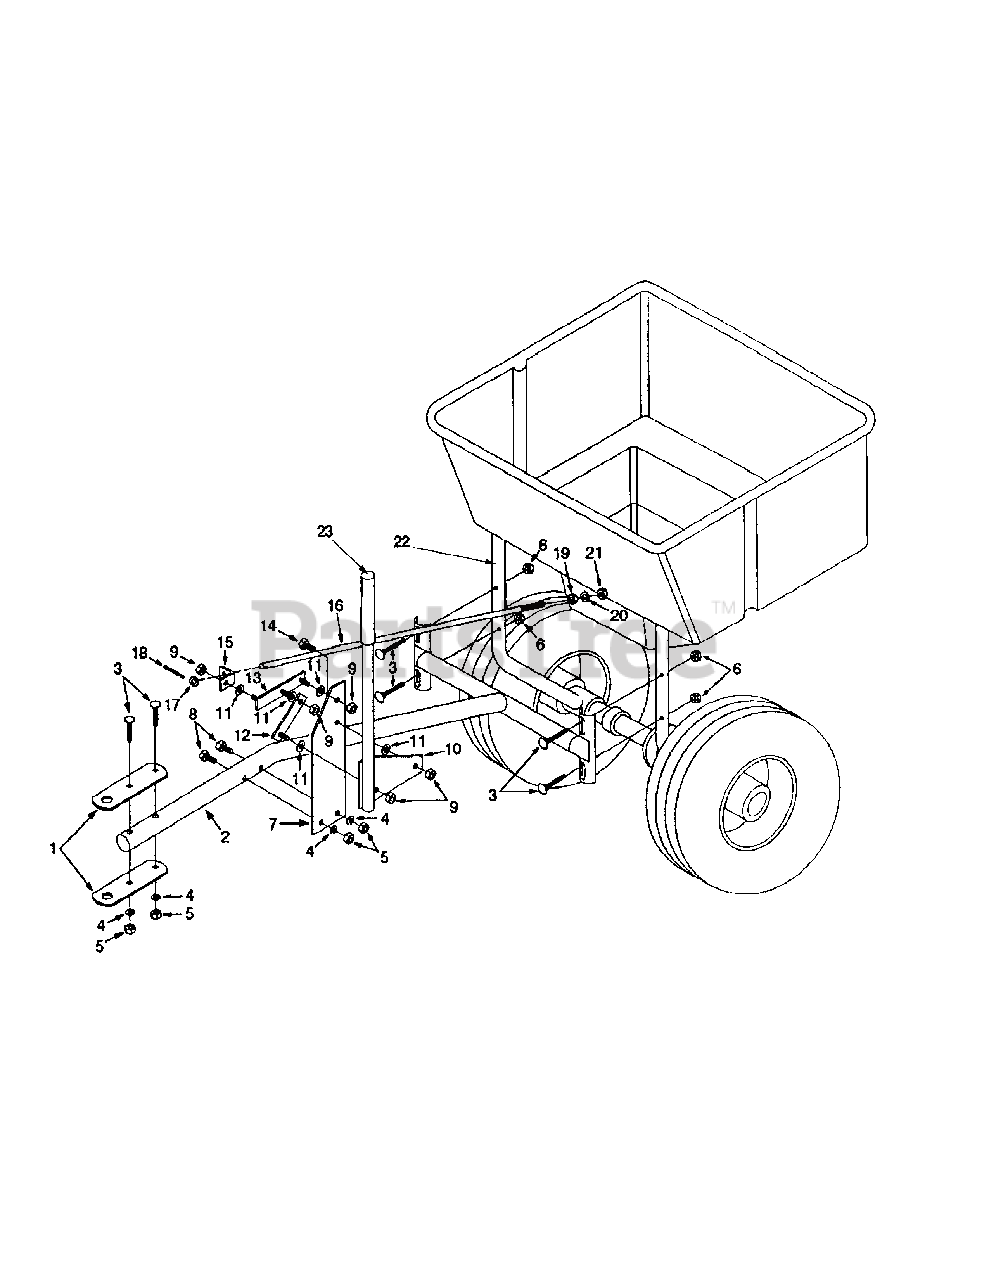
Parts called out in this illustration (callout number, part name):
1	Hitch Plate
2	Towbar
3	Carriage Bolt, 1/4-20 x 1-1/2, SS
4	Lock Washer, 1/4, SS
5	Hex Nut, 1/4-20, SS
6	Hex Nut, 1/4-20 w/Serrated Flange, SS
7	Stand-Off, Pivot handle
8	Cap Screw, 1/4-20 x 1-1/2 Hex Head, SS
9	Hex Nut, 1/4-20 Nylock, SS
10	Pivot Handle
11	Flat Washer, 1/4, SS
12	Single Link
13	Double Link
14	Cap Screw, 1/4-20 x 3/4 Hex Head
15	Pivot Angle
16	Rod, Pivot Handle
17	Flat Washer, 5/16, SS
18	Roll Pin
19	Hex Nut, 5/16-18, SS
20	Lock Washer, 5/16, SS
21	Nylock, Hex Nut, 5/16-18
22	Uni-Frame, Epoxy Finish
